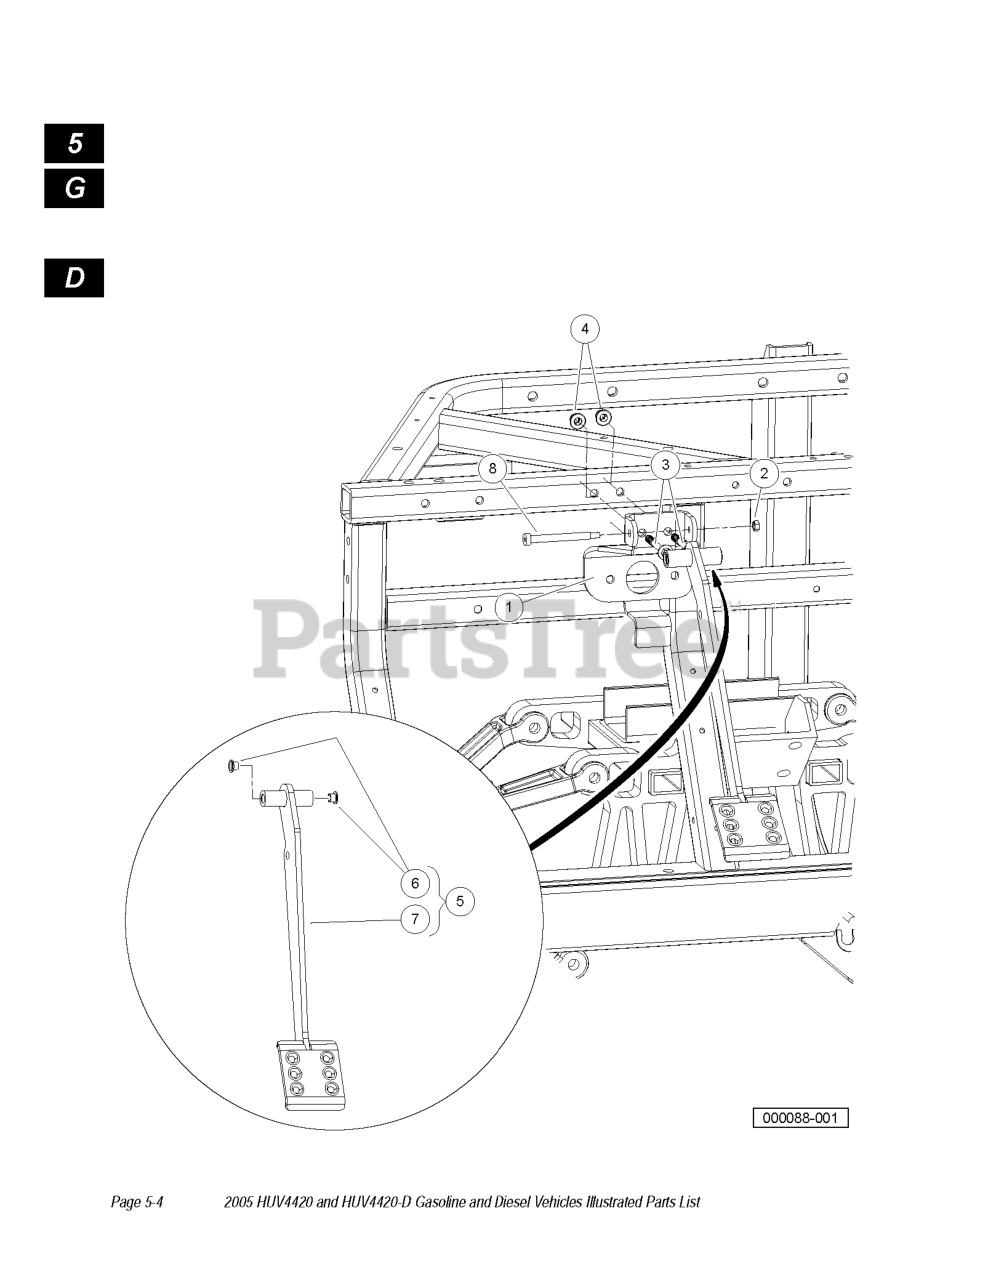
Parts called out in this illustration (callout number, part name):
1	BRACKET, PEDAL, BRAKE
2	NUT M6X1 MECH DEF CENTER
3	BOLT FLG, M8X1.25X65
4	LOCK NUT, FLG M8 X 1.25 NYLON
6	BUSHING, GREASELESS
7	WELDMENT, PEDAL, BRAKE, HUNG
8	BOLT, SHOULDER, M8 X 70, HC
